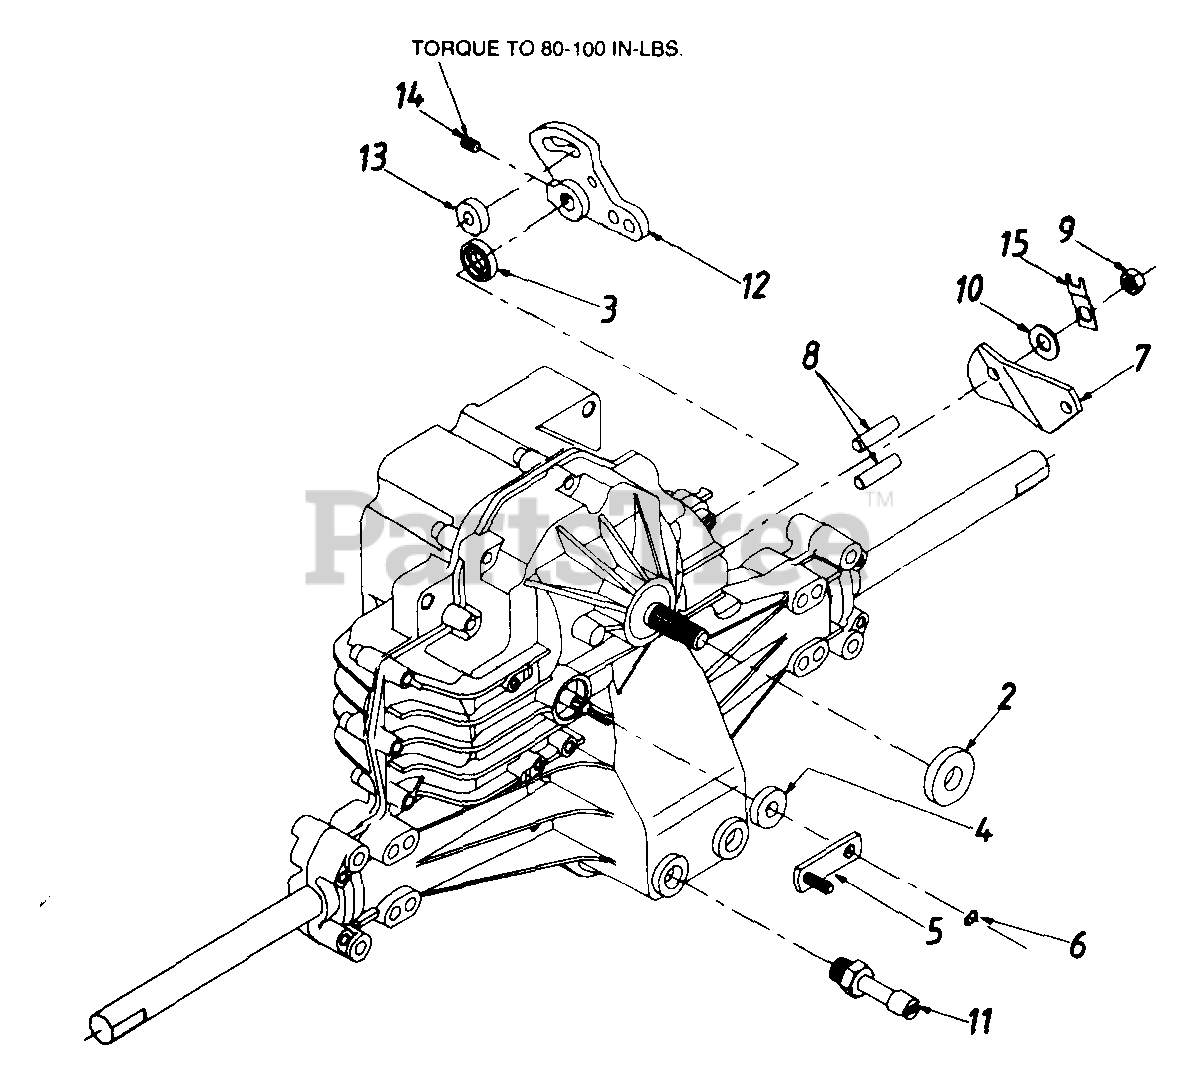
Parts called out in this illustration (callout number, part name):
2	Seal - Lip
3	Seal - Lip
4	Seal - Lip 10 X 25 X 7
5	Arm - Bypass
6	Ring - Retaining
7	Arm - Actuating
8	PIN-ACTUATING
9	Nut - Hex Lock 5/16-24 UNJC
10	Washer 7/16" x 7/8" x .060"
11	Breather Ass'y.
12	Arm - Control
13	Puck - Dampener
14	Set Screw
15	Strap, Locking
